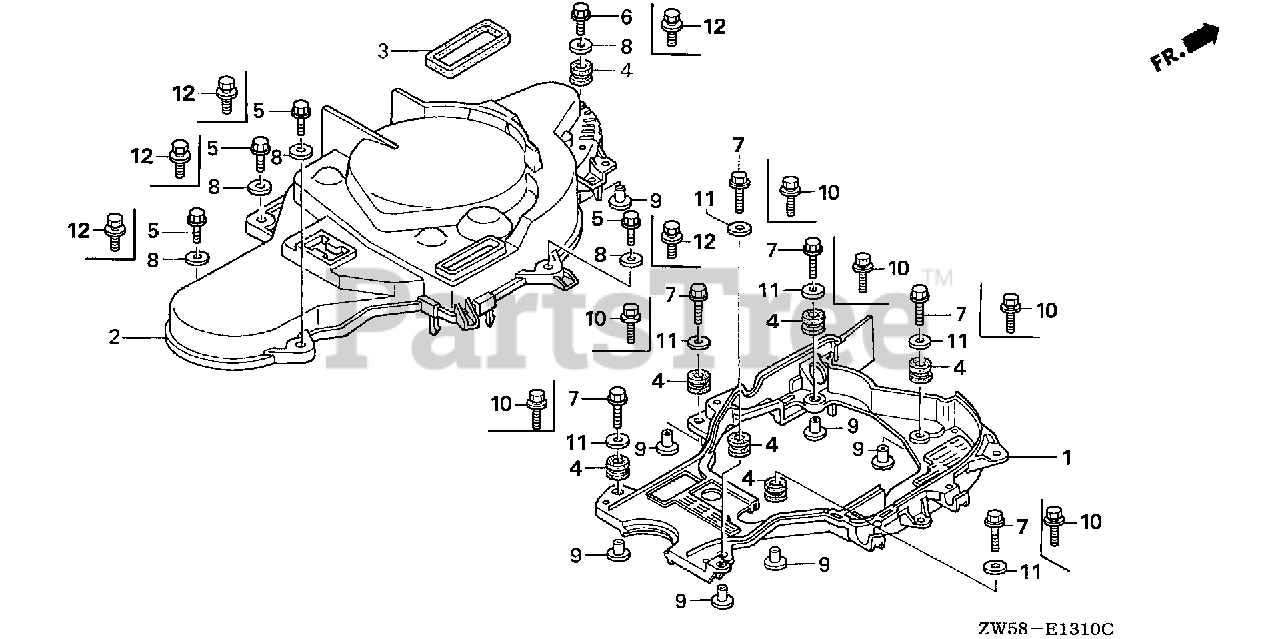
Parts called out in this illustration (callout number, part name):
1	COVER, TIMING BELT (LOWER)
2	COVER, TIMING BELT (UPPER)
3	RUBBER, SEAL
4	GROMMET, CASE (LOWER)
5	BOLT, FLANGE (6X20)
6	BOLT, FLANGE (6X22)
7	BOLT, FLANGE (6X25)
8	WASHER, PLAIN (6MM)
9	COLLAR, MODULE IGNITION CONTROL CASE (CDI)
11	WASHER, PLAIN (6MM)
